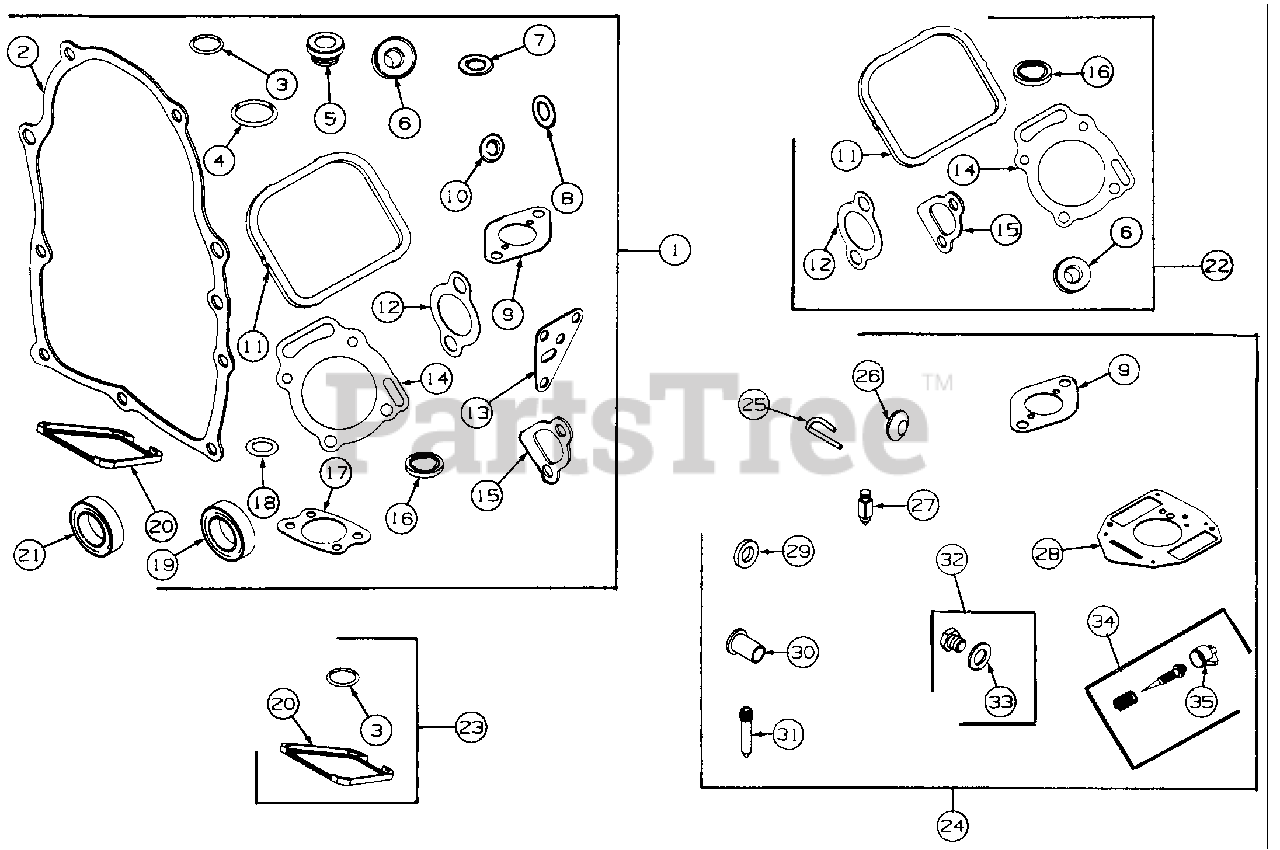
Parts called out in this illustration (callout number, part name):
1	Gasket Set
2	Gasket, Crankcase
3	Seal, Breather Tube
4	Seal, O-Ring
5	Seal, Fill Tube
6	Washer
7	Seal, O-Ring, Crankcase Cover
8	Seal, O-Ring, Oil Pump
9	Gasket, Intake
10	Seal O-Ring, Oil Pump Screen
11	Gasket, Valve Cover
12	Gasket, Exhaust
13	Gasket, Filter Adapter
14	Gasket, Cylinder Head
15	Gasket, Intake
16	Seal, Fill Plug
17	Gasket, Air Cleaner
18	Seal, Governor Shaft
19	Seal, Oil
20	Gasket, Breather
21	Seal, Oil
22	Gasket Set, Valve
23	Gasket Set, Breather
24	Overhaul Kit, Carburetor
25	Pin, Float Hinge
26	Plug, Welch
27	Valve, Fuel Inlet
28	Gasket, Carburetor Body
29	Collar, Throttle
30	Collar, Choke
31	Nozzle, Carburetor (Slow Speed)
34	Valve, Idle Adjust
35	Cap, Limiter
